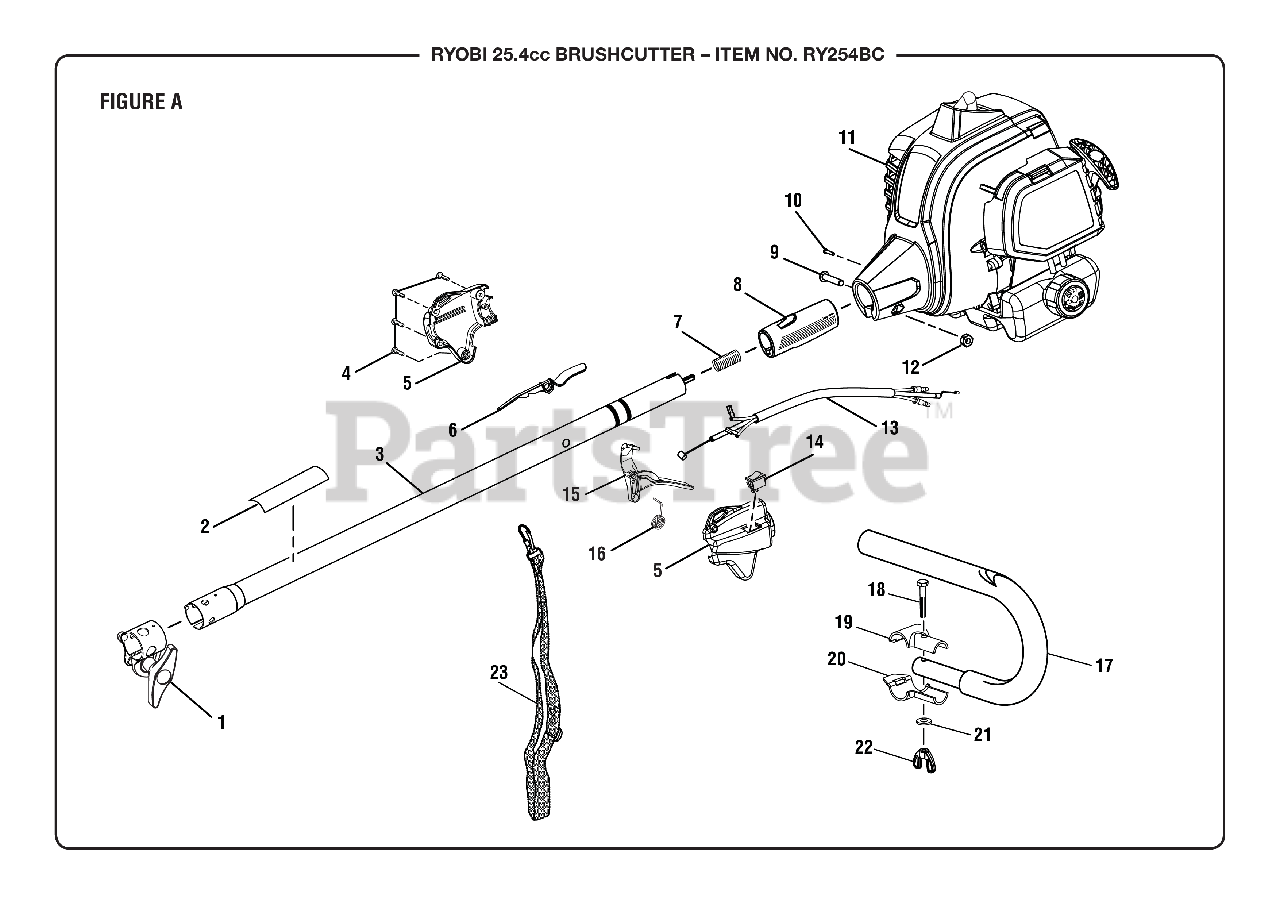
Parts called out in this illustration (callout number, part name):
1	Boom Clamp Assembly
2	Warning Icon Label
3	Upper Boom Assembly
4	Screw (M4 x 20 mm, T20 Torx Pan Hd. S.T.)
5	Control Handle Assembly (Inc. Key No. 6)
6	Trigger Lock
7	COMPRESSION SPRING
8	Rear Handle Grip
9	Screw (M6 x 30 mm, T27 Torx Button Hd.)
10	Screw (M4 x 8 mm, T25 Torx Pan Hd. T.F.)
11	Powerhead Assembly w/Labels
12	Hex Nut (M6.3 x 1)
13	Throttle Cable and Wire Assembly
14	Stop Switch (Momentary Contact)
15	Throttle Trigger
16	Torsion Spring (Throttle Trigger)
17	â?oJâ? Handle w/Grip
18	BOLT (HANDLE) (1/4-20 x 1-1/2 in. HEX HD.)
19	Handle Bar Clamp Top â?oJâ?
20	Handle Bar Clamp Bottom â?oJâ?
21	Washer (ID7.25 x OD16 x 1.5t)
22	Wing Nut (1/4-20, Plastic)
23	Shoulder Harness Assembly
